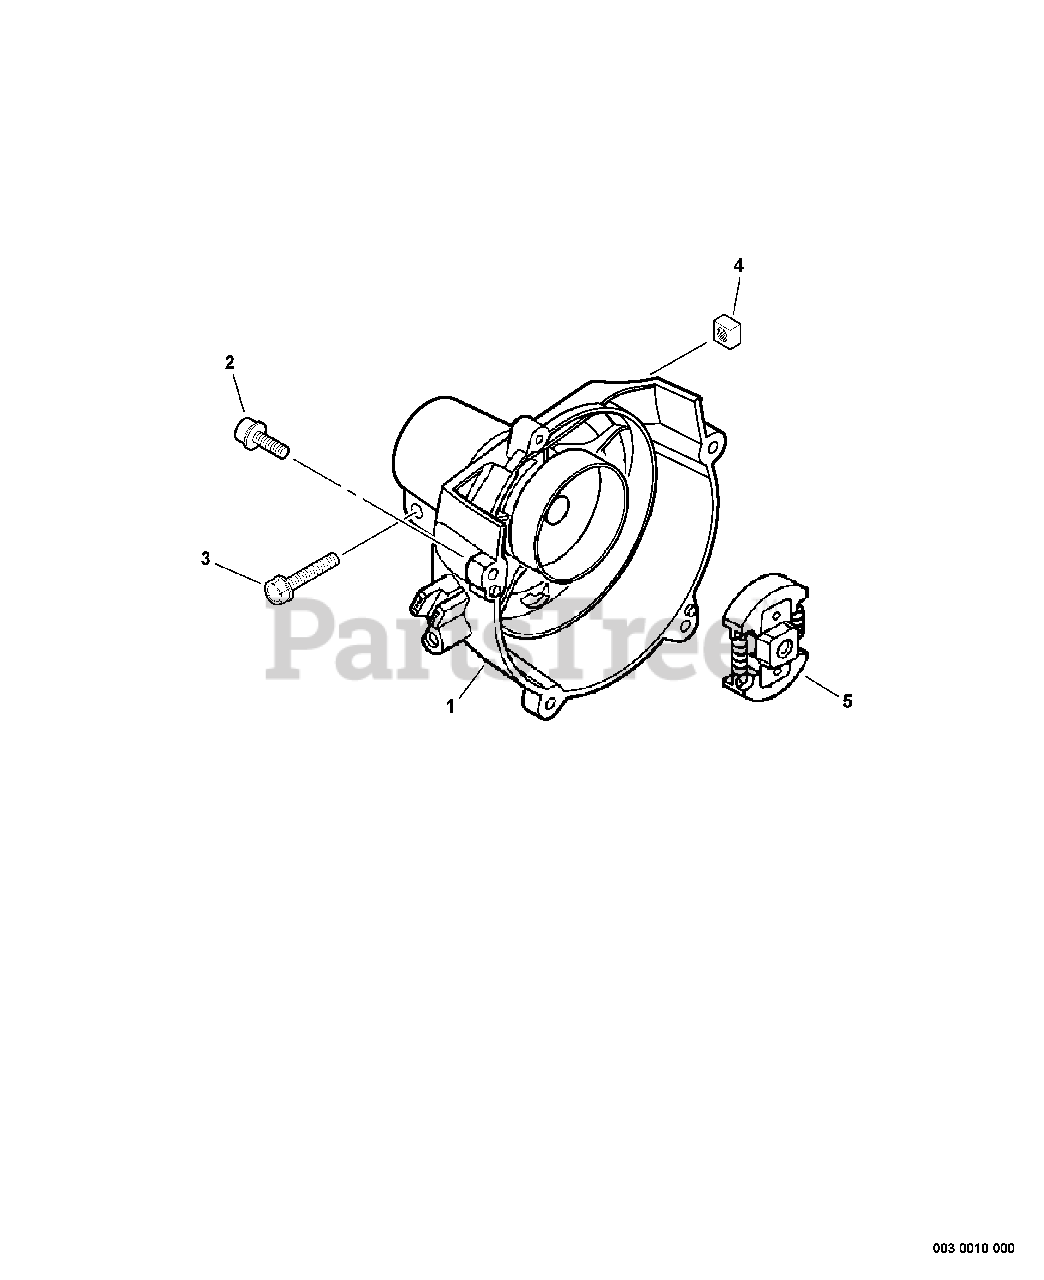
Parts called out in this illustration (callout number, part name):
1	FAN CASE ASSY
2	BOLT - 4X16
3	SCREW - 5X28
4	NUT - 5 -- SQUARE
5	CLUTCH ASSY
